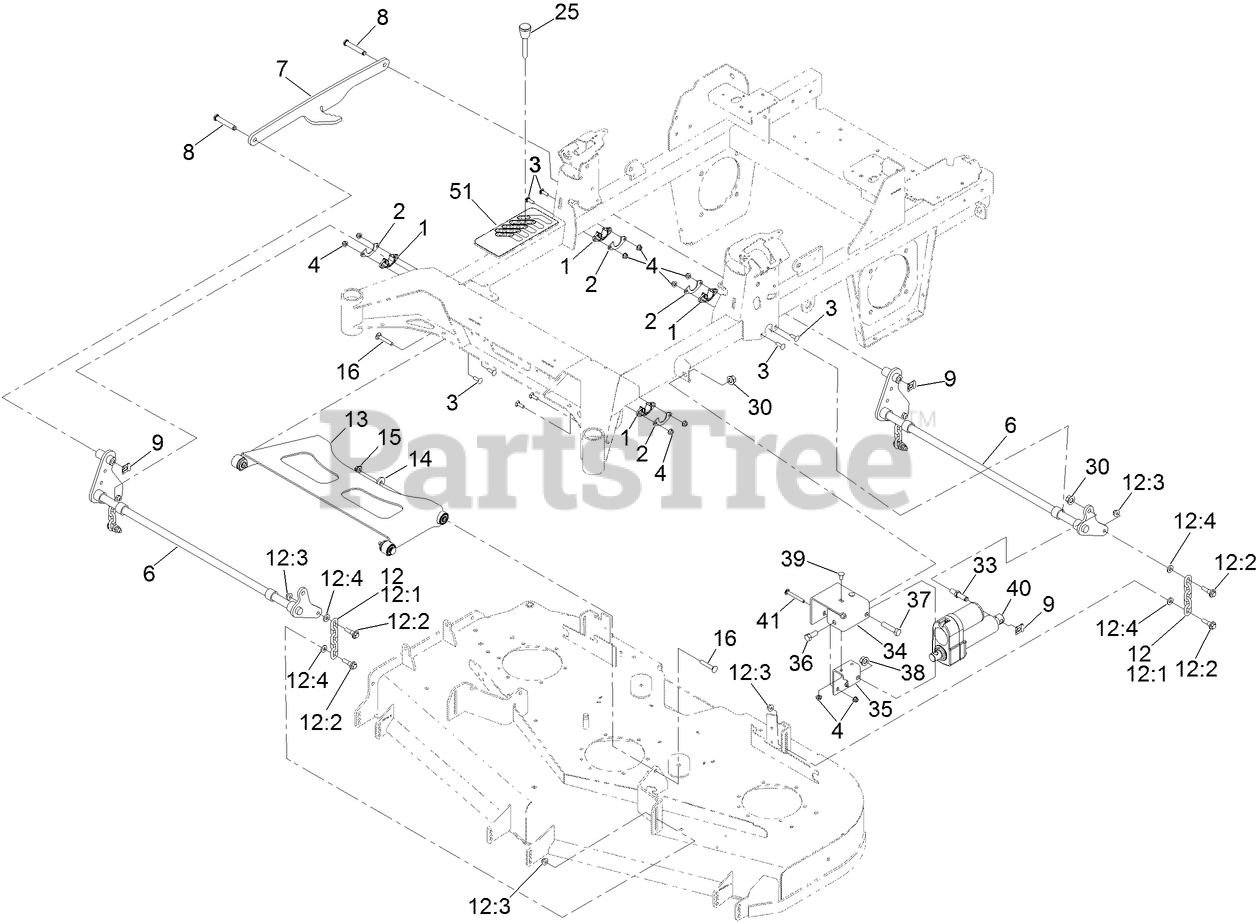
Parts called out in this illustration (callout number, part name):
1	BUSHING-FLANGE
2	GUSSET-LIFT, DECK
3	SCREW-CARR
4	NUT-HF, NI
6	DECK LIFT SHAFT ASM [BLACK]
7	LINK-LIFT
8	PIN-CLEVIS
9	CLIP-PIN
12	DECK CHAIN ASM
12:1	CHAIN-LIFT, DECK
12:2	BOLT-SHOULDER
12:3	NUT-HF, NI
12:4	SPACER
13	ASM-DECK STRUT W/ BUSHINGS
14	WASHER
15	NUT-FLANGE, NI
16	SCREW-CARR
25	PIN-HOC
30	NUT-LOCK
33	PIN-PIVOT, ACTUATOR
34	BRACKET-MOUNT, OUTER
35	BRACKET-MOUNT, INNER
36	SCREW-HHF
37	SCREW-HHF
38	NUT-LOCK
39	BOLT-CARR
40	ACTUATOR-LINEAR
41	SCREW-CARR
51	DECAL-HOC
